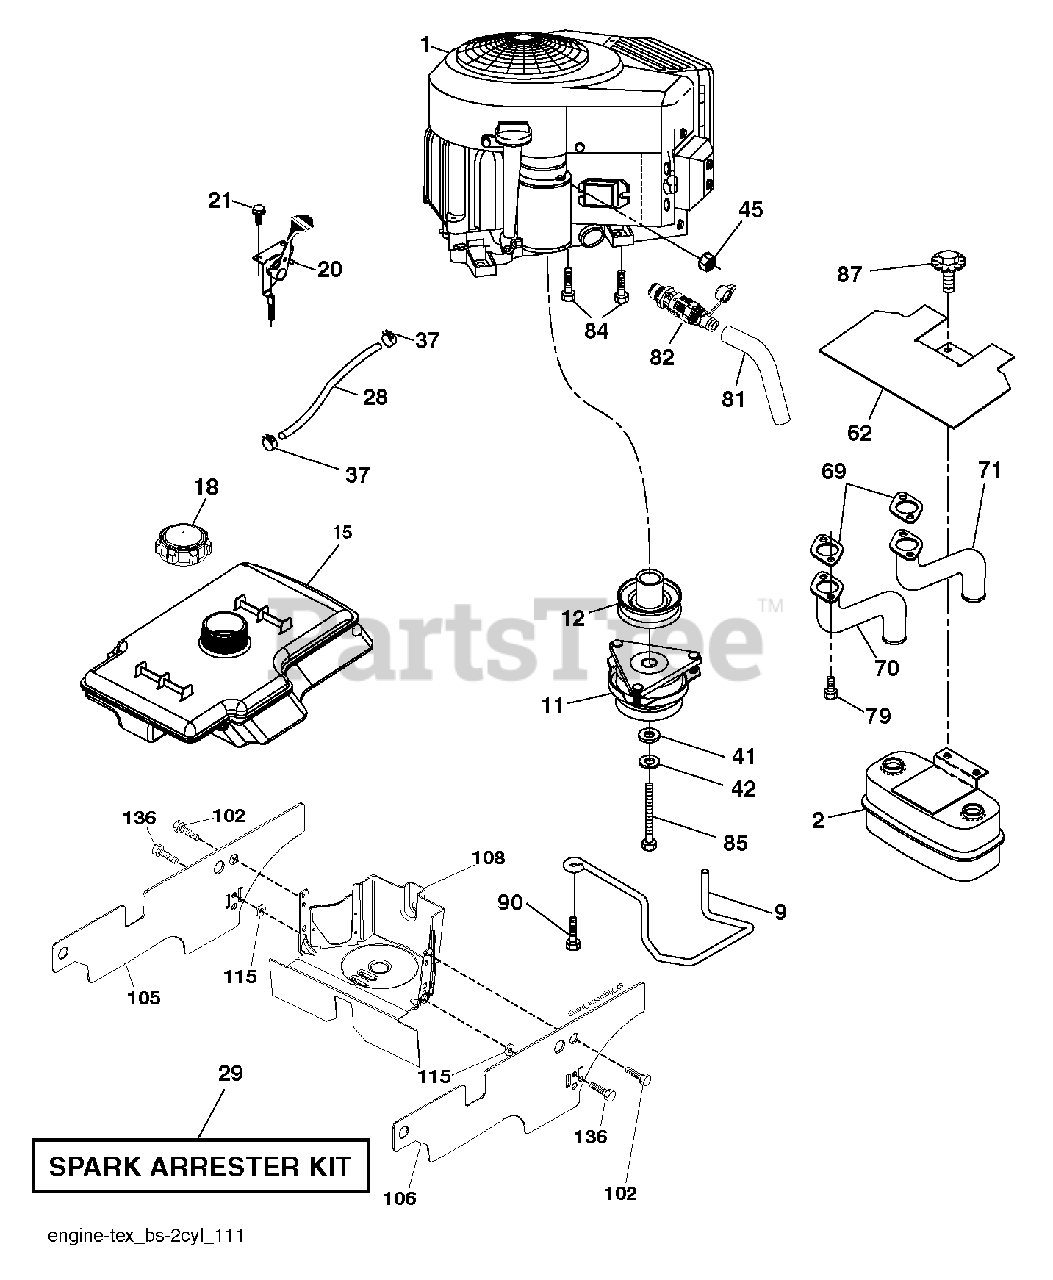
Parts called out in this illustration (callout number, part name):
2	MUFFLER.ASM.TWN.EXTNDED.DFLCTR
9	KEEPER BELT ENGINE
11	RB.CLUTCH.OGURA.4.4.PD
12	PULLEY.ENGINE.TUFFTORQ
15	FUEL TANK
18	CAP.ASSY.FUEL.3".N-EPA.BLK.428
20	CONTROL.TH/CK.COBRA.B&S.TWN.
21	SCREW.#10 X 0.750.BOS
28	REPL BY 532 00 85-43
29	KIT.SPARK ARRESTOR 794945 B&S
37	HOSE CLAMP
42	LOCKWASHER
45	NUT
62	SHIELD.HEAT.MUFFLER
69	GASKET.MUFFLER
70	EXHAUST.TUBE.LH.BS/TWIN
71	EXHAUST.TUBE.RH.B&S.TWIN.INTEK
79	SCREW.SOCKET.HEAD.5/16-18
81	TUBE, DRAIN OIL ASM.
82	VALUE.OIL.DRAIN
84	SCREW.3/8-16
85	BOLT HEX 7/16-20X4-1/4"
87	BOLT, 5/16-18 X 1 3/4
90	SCREW 3/8-16X1
102	SCREW
105	SHIELD.SIDE.LH.3842"TEX FRENCH
106	SHIELD.SIDE.RH.3842"TEX FRENCH
108	ENGINE COVER
115	PALNUT 1/4
136	SCREW.1/4-20X5/8
